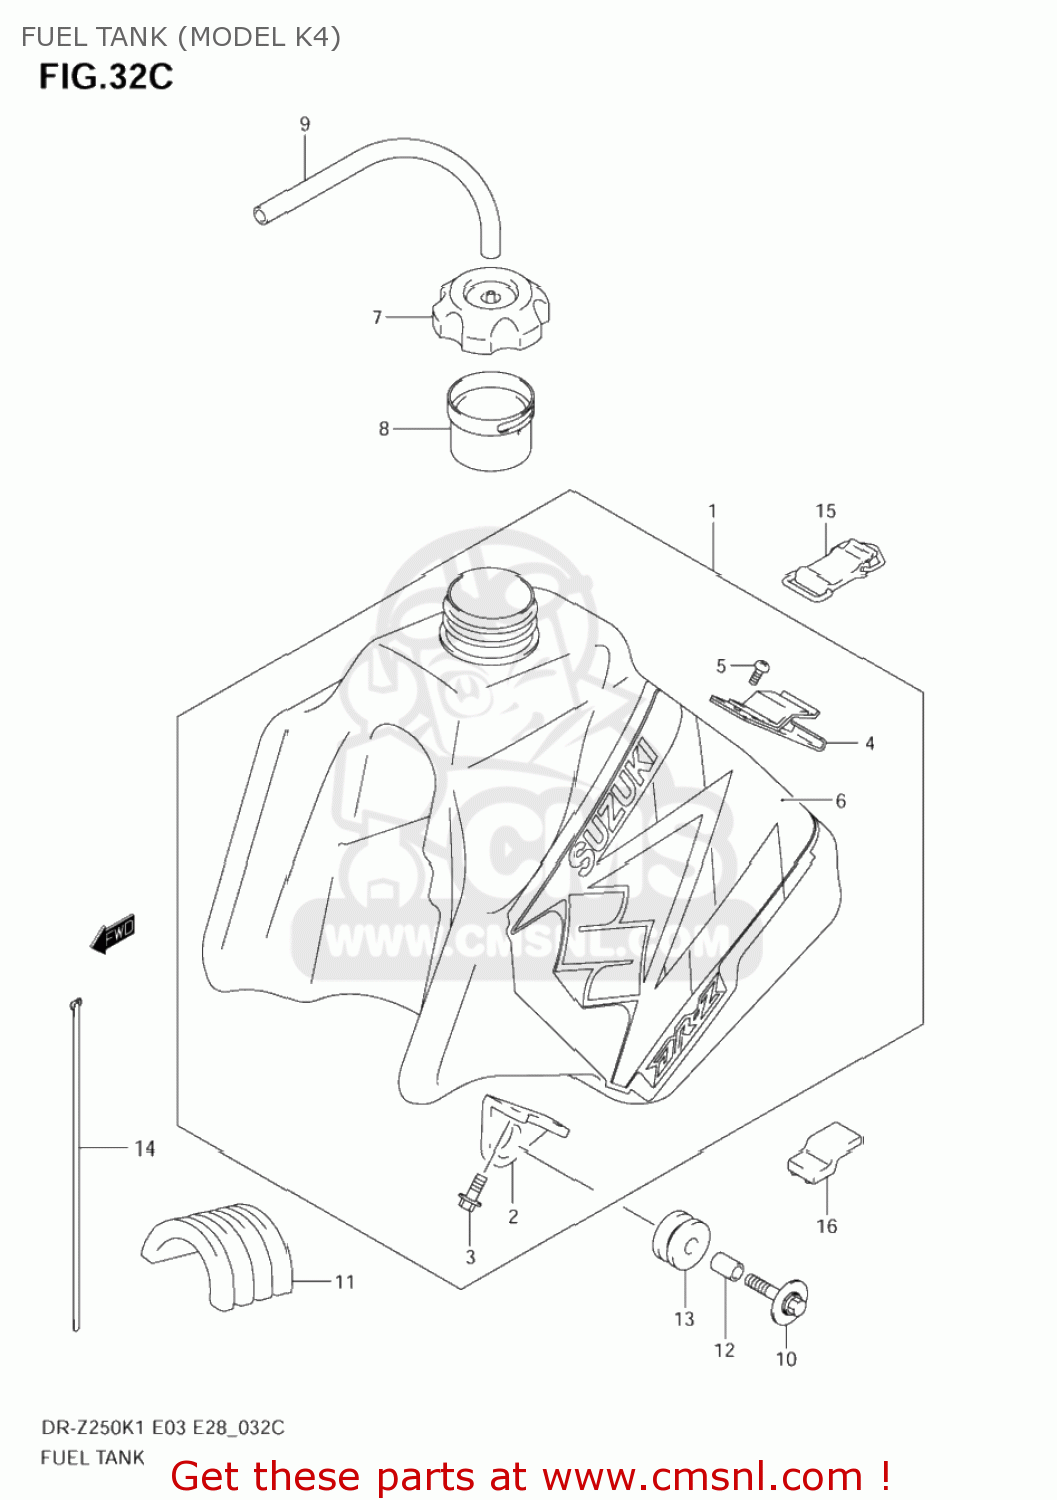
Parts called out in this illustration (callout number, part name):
1	TANK ASSY,FUEL(YELLOW)
2	BRACKET,FUEL TANK FR
3	BOLT
4	BRACKET,FUEL TANK RR
5	SCREW 6X12
6	TAPE SET,FUEL TANK
7	CAP ASSY,FUEL TANK FILLER
8	TUBE,FILLER INLET
9	HOSE(5X8.2X600)
10	BOLT(6X30)
11	CUSHION,FUEL TANK
12	SPACER(6.5X9X13.5)
13	CUSHION,MUFFLER
14	CLAMP(L:300)
15	BAND,FUEL TANK RR
16	CUSHION,FUEL TANK
